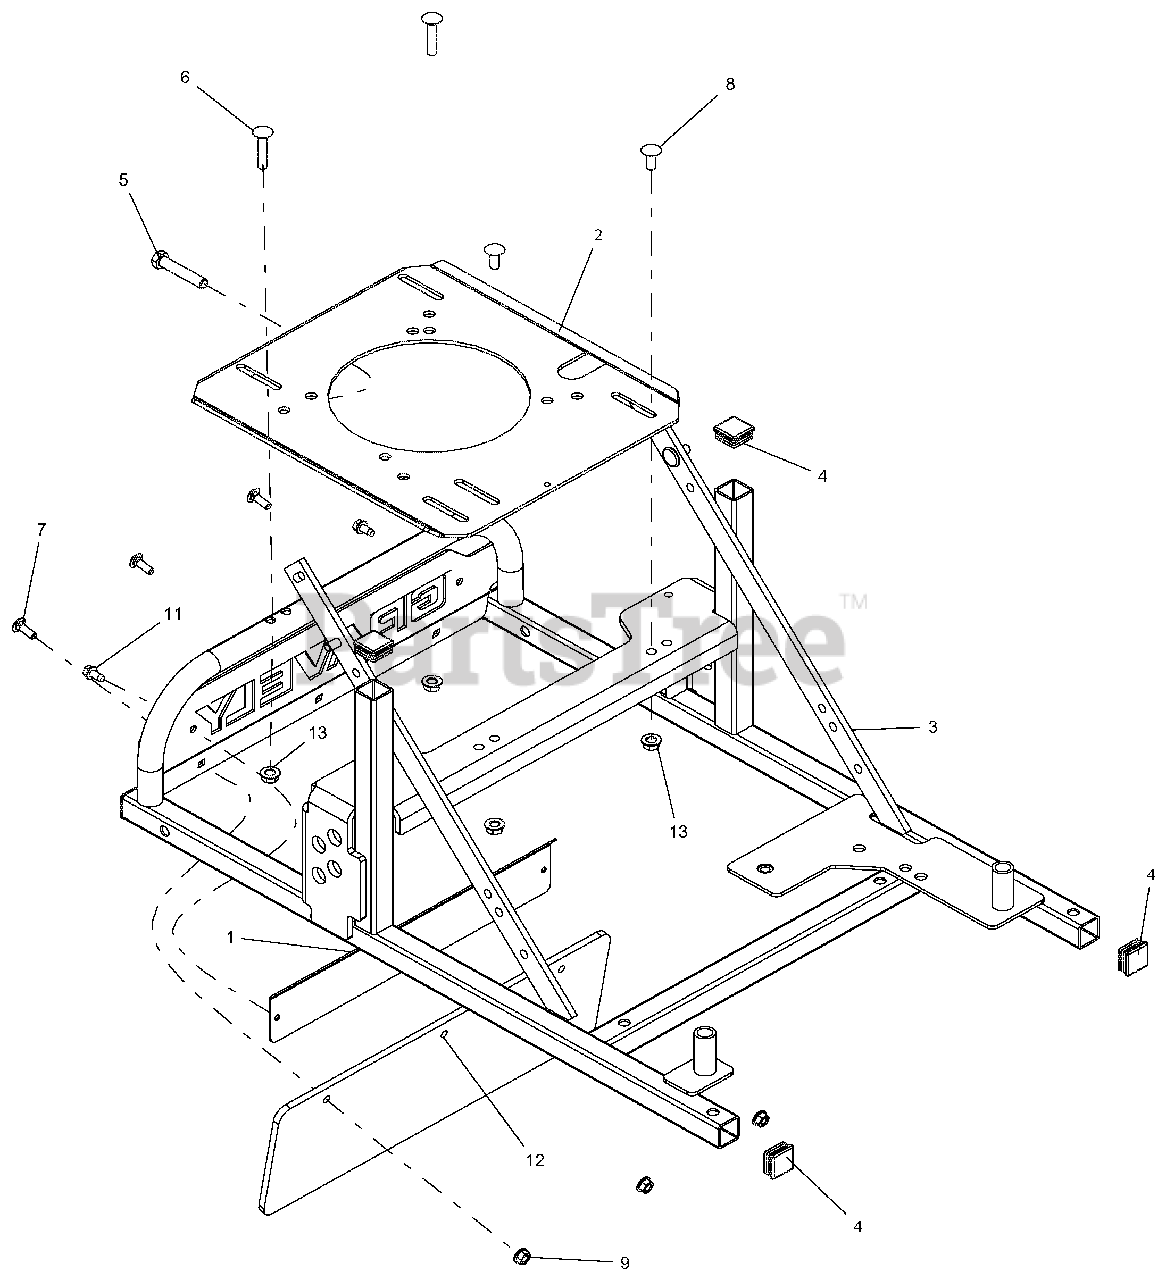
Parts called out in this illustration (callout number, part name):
1	BACKER, GRAVELY
2	PLATE, ENGINE (RED)
3	WLDMT, HIGH WHL MWR FRAME
4	CAP PLUG FOR 1" TUBE 14GA
5	BLT-HEX .38-16X2.00 FTH GR5 YWZC
6	BLT-RDHDSQNK .31-18X1.50 G5 YWZC
7	BLT-RDHDSQNK .25-20X.75 G5 YWZC
8	BLT-RHDSSQNK .31-18X.75 G5YZ
9	NUT, LK-TOP-FLG .25-20 YWZC
11	SCR-TAP .25-20X.50 HWH TR YWZ
12	GUARD, RUBBER DEBRIS
13	NUT, LK-TOP-FLG .312-18 YWZC
